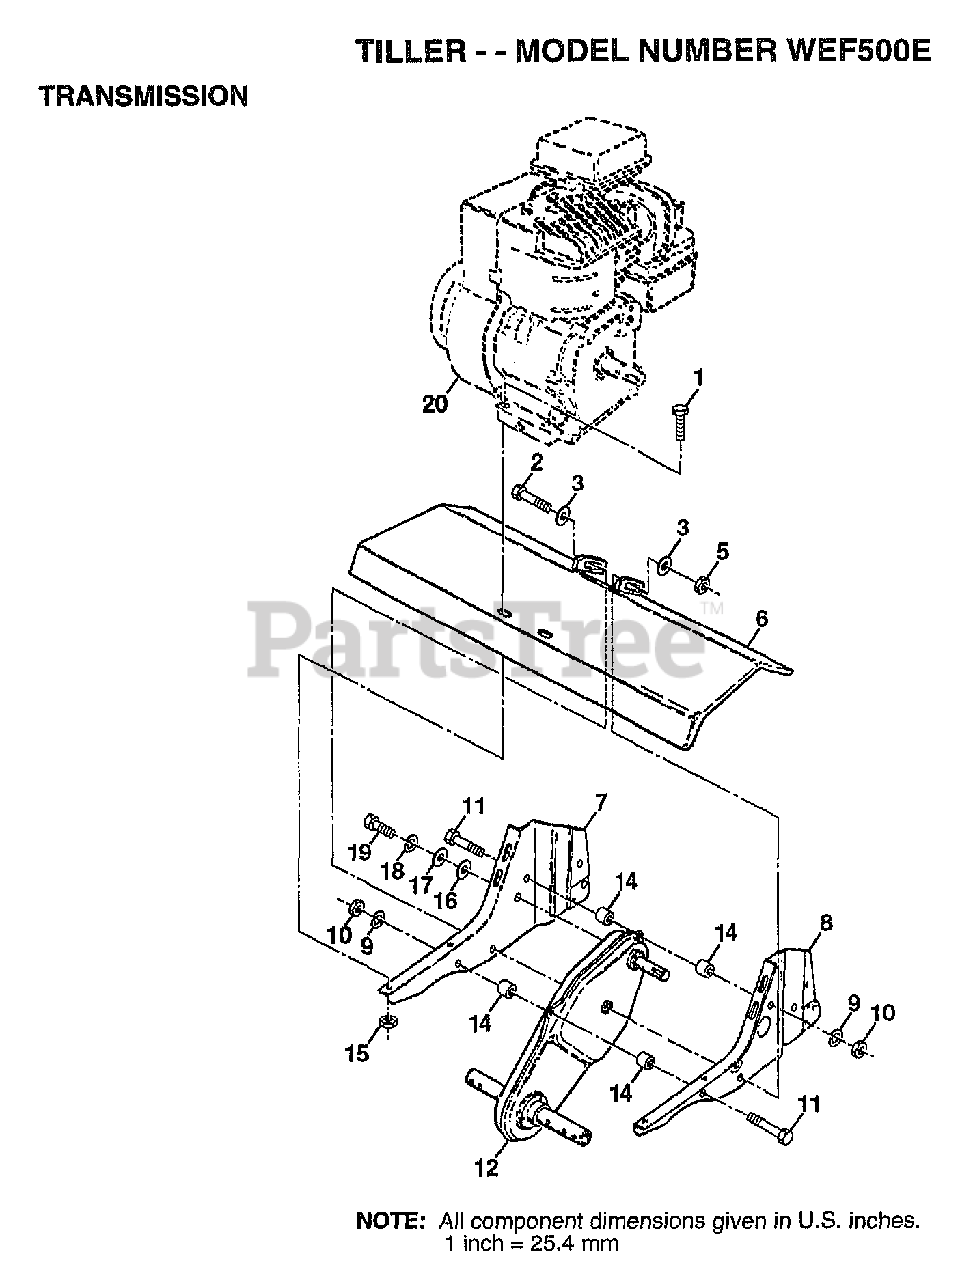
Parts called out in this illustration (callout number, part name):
1	BOLT.HEX.5/16-1.5
2	BOLT HEX 3/8-16
3	WASHER
5	NUT
6	SHIELD.PNT.TINE
8	ENGINE BRKT LH TI
9	LOCKWASHER
10	NUT.HEX.5/16-18
14	SPLIT SPACER RT
16	WASHER
17	WASHER
18	LOCKWASHER
19	BOLT
